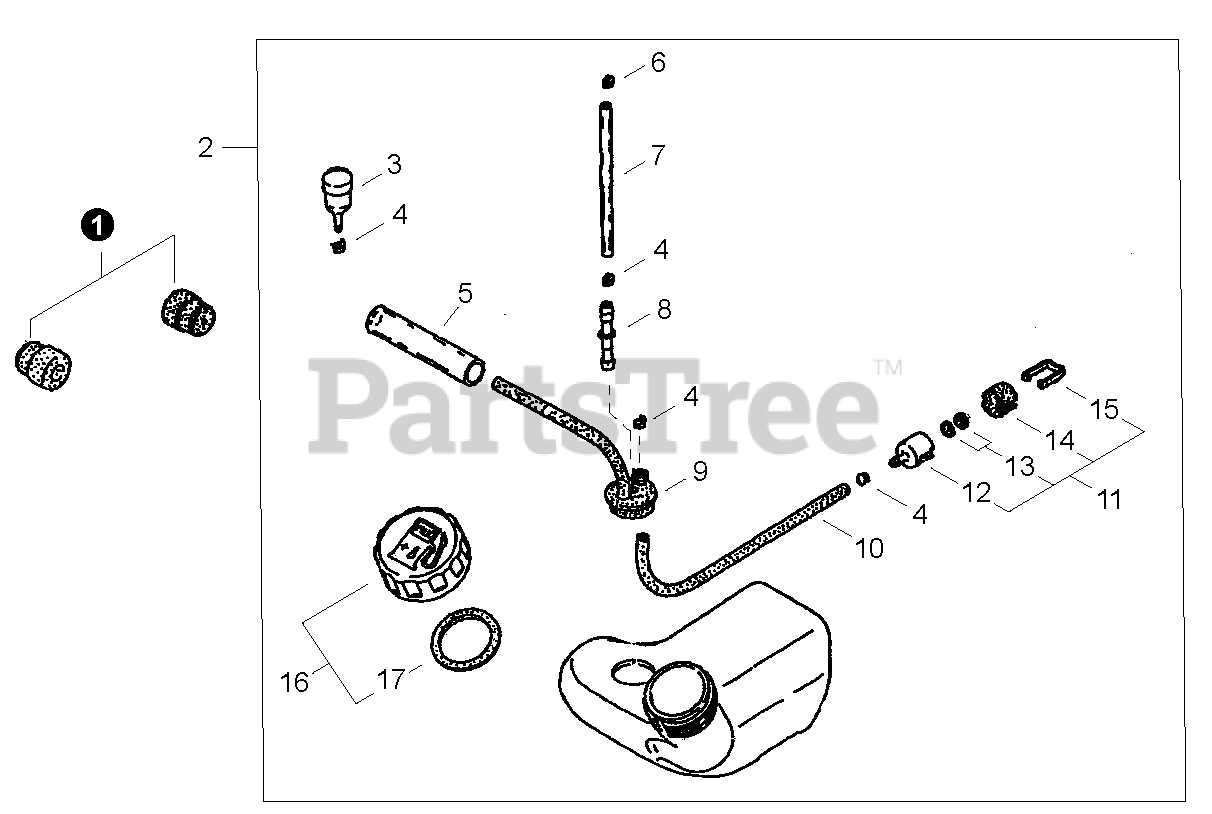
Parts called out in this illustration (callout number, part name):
1	CUSHION
2	FUEL TANK ASSY
3	VENT, FUEL TANK
4	CLIP - 6
5	PIPE - 2.4X5X170 -- CLEAR
6	CLIP - BUTTERFLY
7	PIPE - RETURN
8	CONNECTOR, PIPE
9	PIPE ASSY
10	PIPE - FUEL
11	FUEL FILTER ASSY
12	WEIGHT, FUEL FILTER
13	STRAINER
14	FILTER, FUEL
15	CLIP
16	CAP ASSY
17	GASKET, CAP
